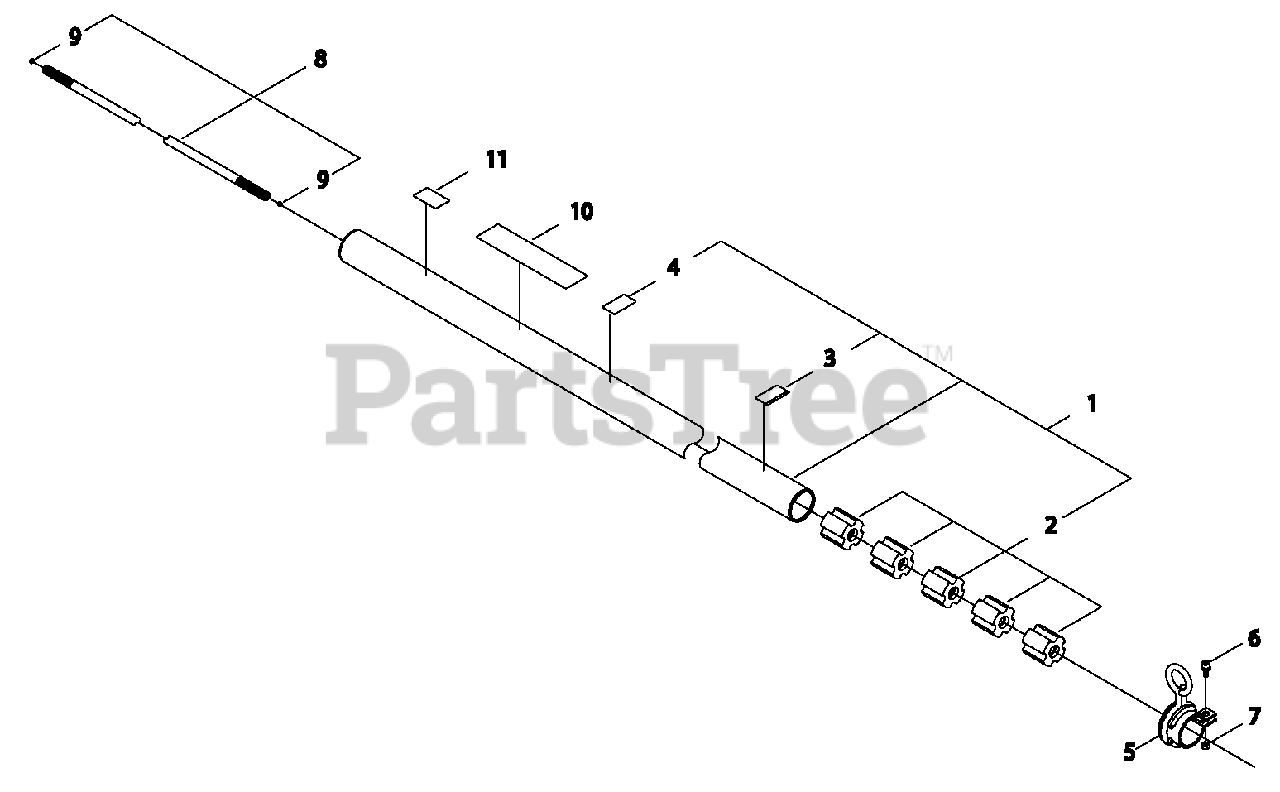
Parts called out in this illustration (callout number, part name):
1	MAIN PIPE ASSY
2	BUSHING
3	LABEL - ALIGNMENT
4	LABEL, HANDLE
5	HANGER
6	BOLT M5×12
7	NUT M5
8	DRIVESHAFT ASSY
9	STOPPER
10	LABEL, CAUTION
11	LABEL, SPEED
